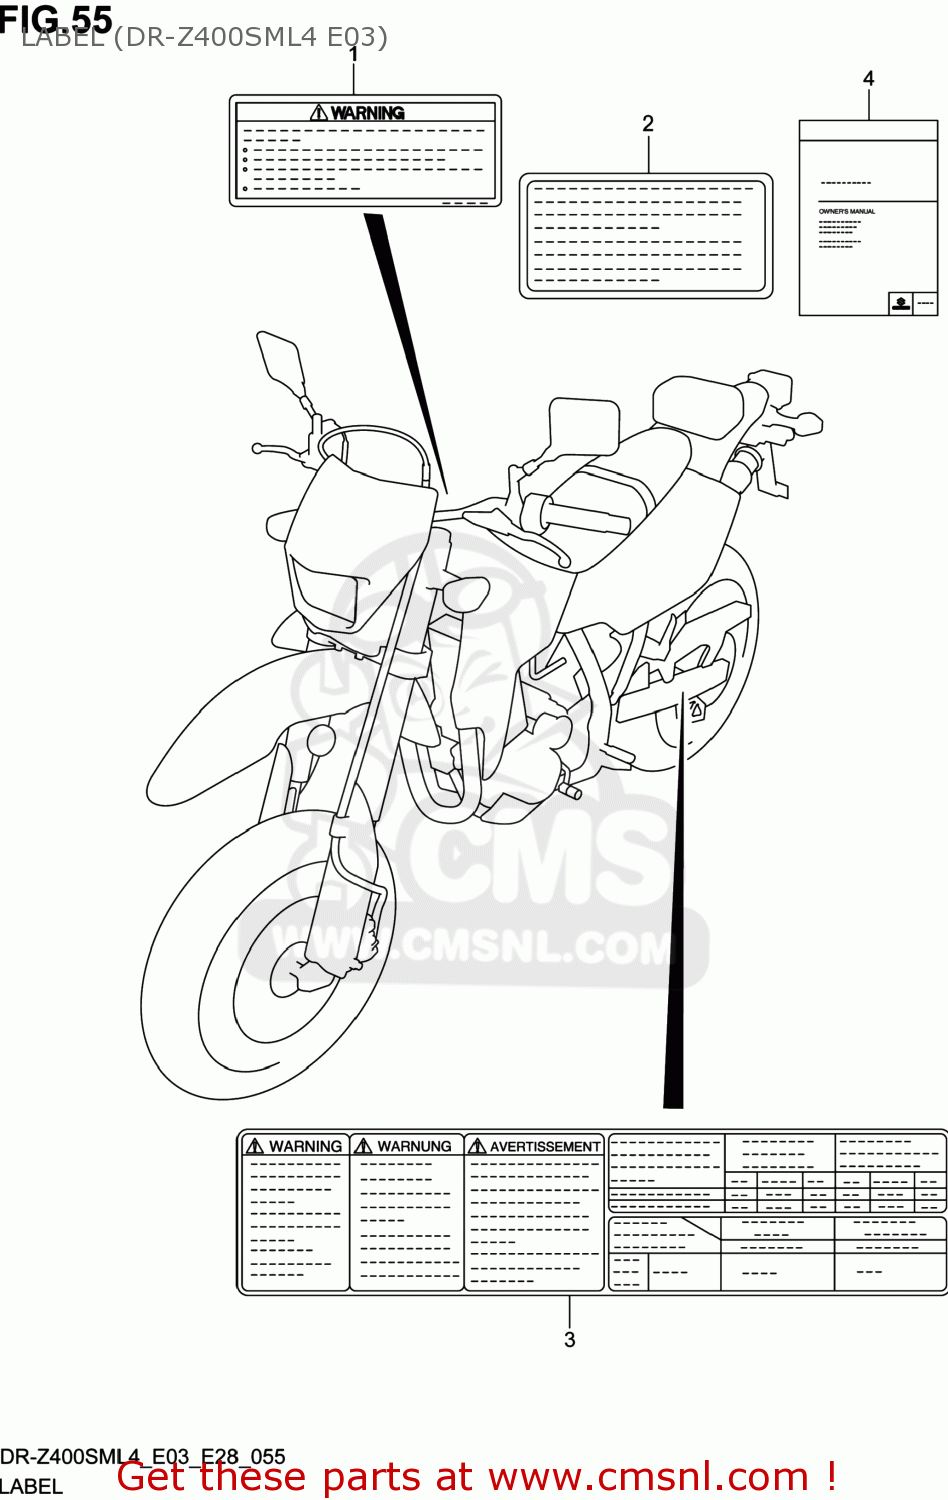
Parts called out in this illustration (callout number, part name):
1	LABEL,GENERAL WARNING
2	LABEL,MANUAL NOTICE
3	LABEL,TIRE INFORMATION
4	MANUAL,OWNER'S
